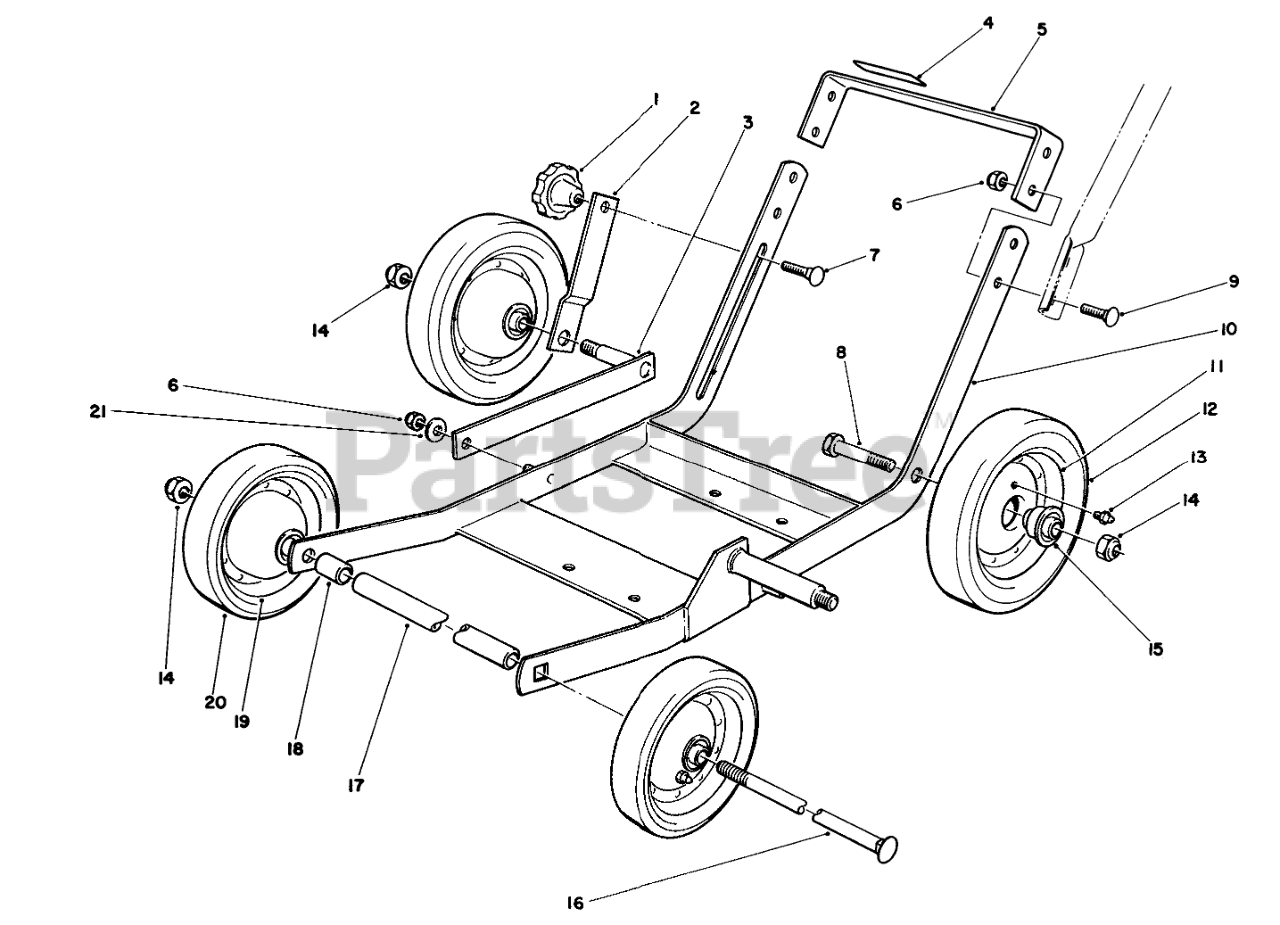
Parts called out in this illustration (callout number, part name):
2	WHEEL LINK R
3	BAR WA RO
4	Decal-Warning
5	Bar-Escutcheon
6	NUT-LOCK, NI
7	SCREW-CARR
8	SCREW-HH
9	SCREW-CARR
10	Frame Assembly
11	Wheel & Tire Assembly-8" (Incl. Ref. #12, 13 & 15)
13	FITTING-GREASE
14	NUT-LOCK, NI
15	FLANGED BEARING
16	CARRIAGE BOLT
17	AXLE SPACER
18	SPACER
19	Wheel & Tire Assembly-7" (Incl. Ref. #13, 15 & 20)
20	TIRE 7"
21	WASHER-FLAT
